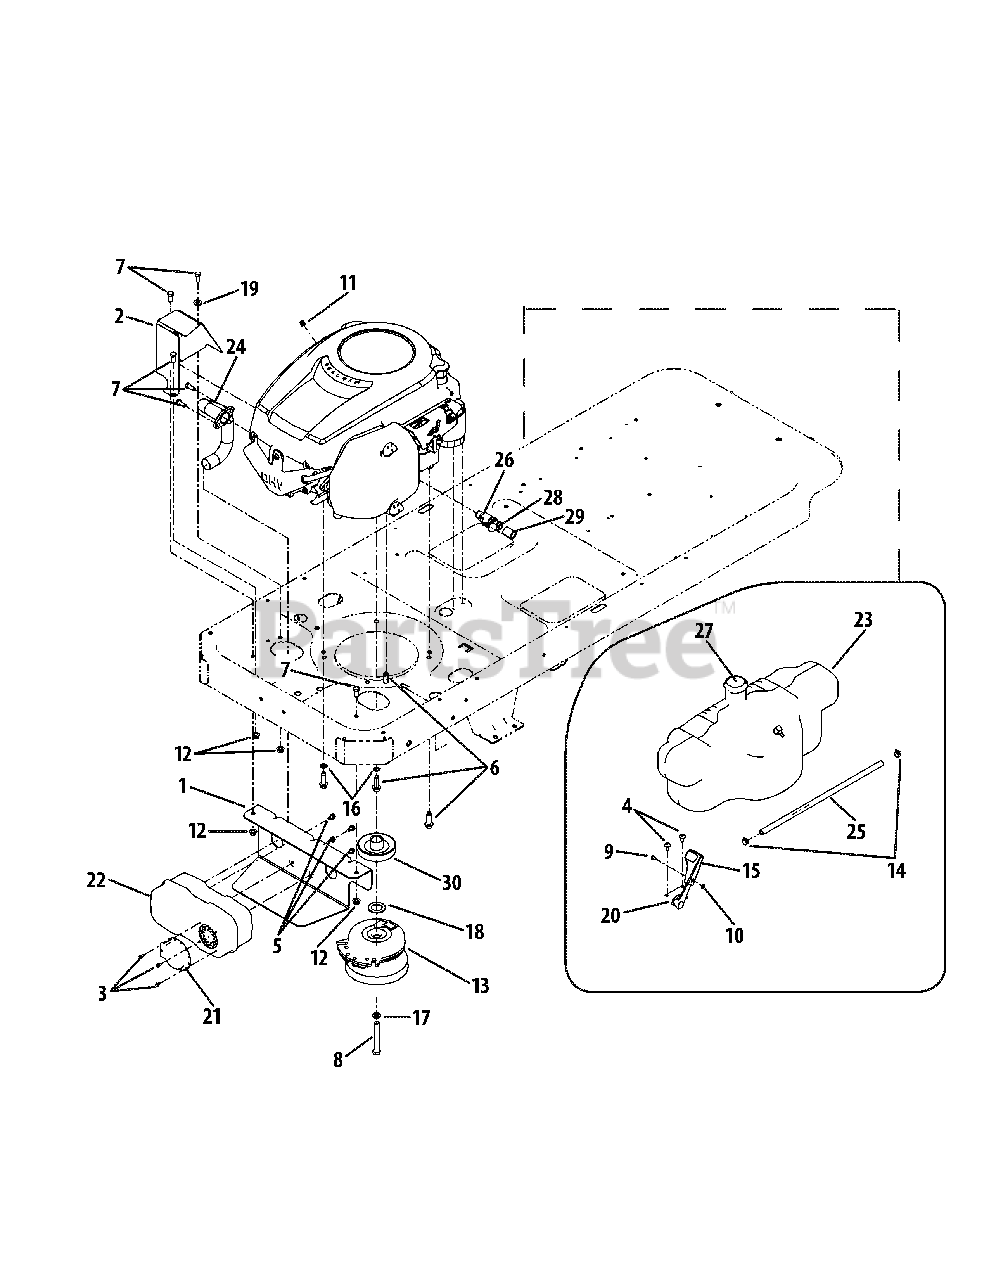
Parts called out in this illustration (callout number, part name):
1	Muffler Mounting Bracket
2	Muffler Tube Heat Shield
3	Hex Washer Head Screw, #8-18 x .5
4	Hex Washer Head Screw, 1/4-14 x
5	Hex Washer Head Screw, 1/4-20 x .5
6	Hex Washer Head Screw, 3/8 -16 x 1.25
7	Hex Cap Screw, 5/16-18 x .75
8	Hex Cap Lock Screw,7/16-20 x 3.25
9	Truss Head Machine Screw, #8-32 x .375
10	Hex Nut, #8-32
11	Hex Sems Nut, 1/4-20
12	Hex Insert Flange Lock Nut, 5/16-18
13	Electric PTO Clutch Assembly
14	Hose Clamp
15	Throttle Control Knob
16	External Tooth Lock Washer, 3/8
17	Lock Washer, 7/16
18	Flat Washer, 1.031 x 1.62 x .095
19	Flat Washer, .344 x .75 x .12
20	Throttle Cable, 39.0 Lg
21	Muffler Deflector
22	Muffler
23	Fuel Tank
24	Exhaust Pipe
25	Low Permeation Fuel Hose
26	Oil Drain Valve
27	Fuel Cap
28	Oil Drain Valve Cap
29	Oil Drain Extension Hose
30	Drive Pulley
